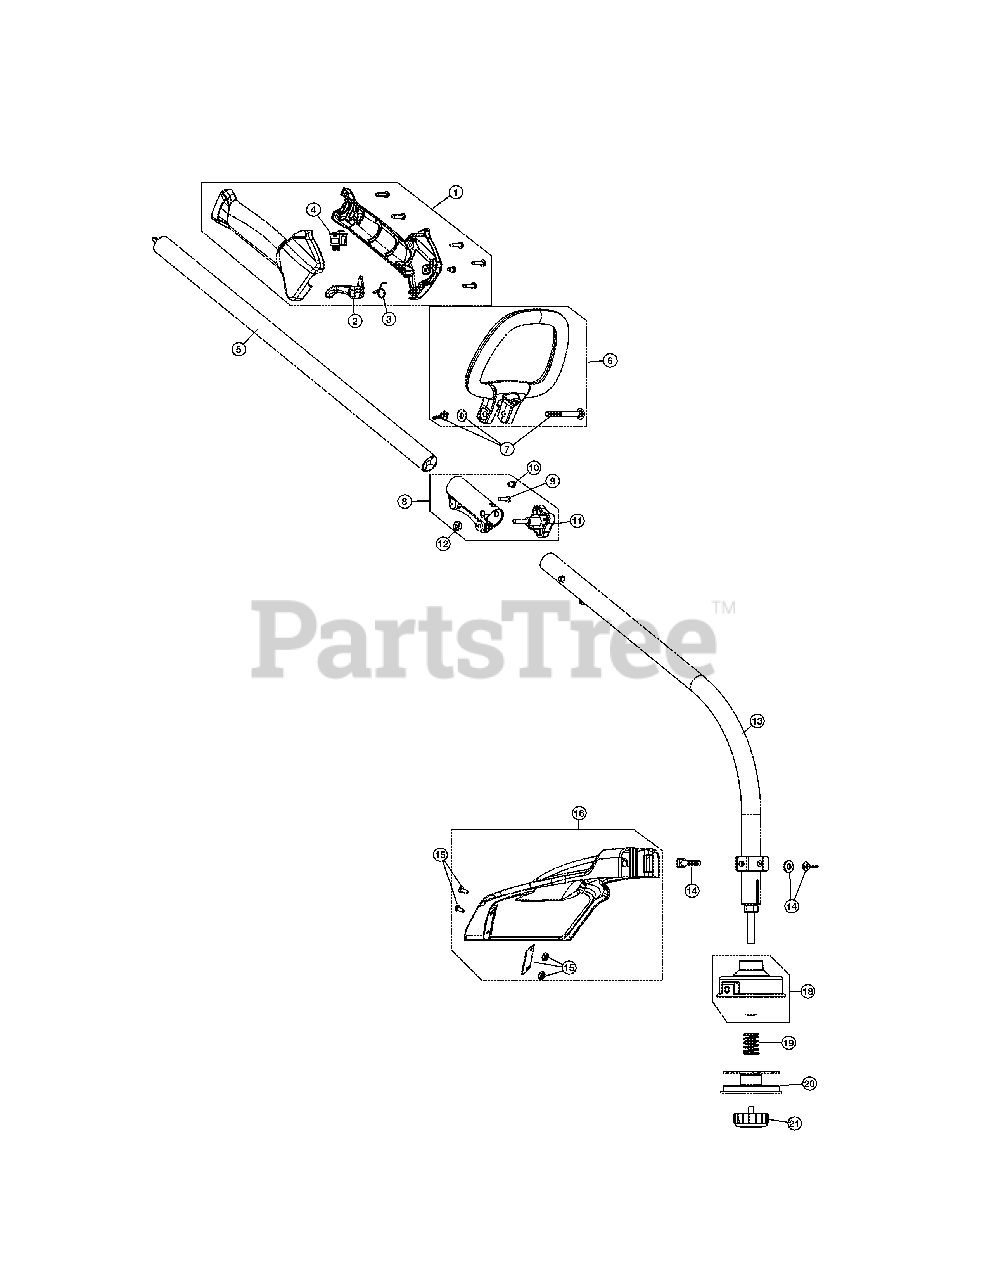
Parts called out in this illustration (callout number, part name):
1	Throttle Housing Assembly (Incl Ref No. 2-4)
3	Throttle Trigger
4	Throttle Trigger Spring
5	Upper Shaft Housing Assembly
6	D-Handle (Incl Ref No. 7)
7	D-Handle Hardware Assembly
8	Split Boom Coupler (Incl Ref No. 9-12)
9	Anti-Rotation Screw
11	Adjustment Knob
12	Knob Retainer Nut
13	Lower Shaft Housing Assembly
14	Shield Mounting Hardware
15	Blade Assembly
16	Shield Assembly (Incl Ref No. 15)
18	Outer Spool Assembly
18	Retainer
20	Inner Reel
21	Bump Head Knob Assembly
